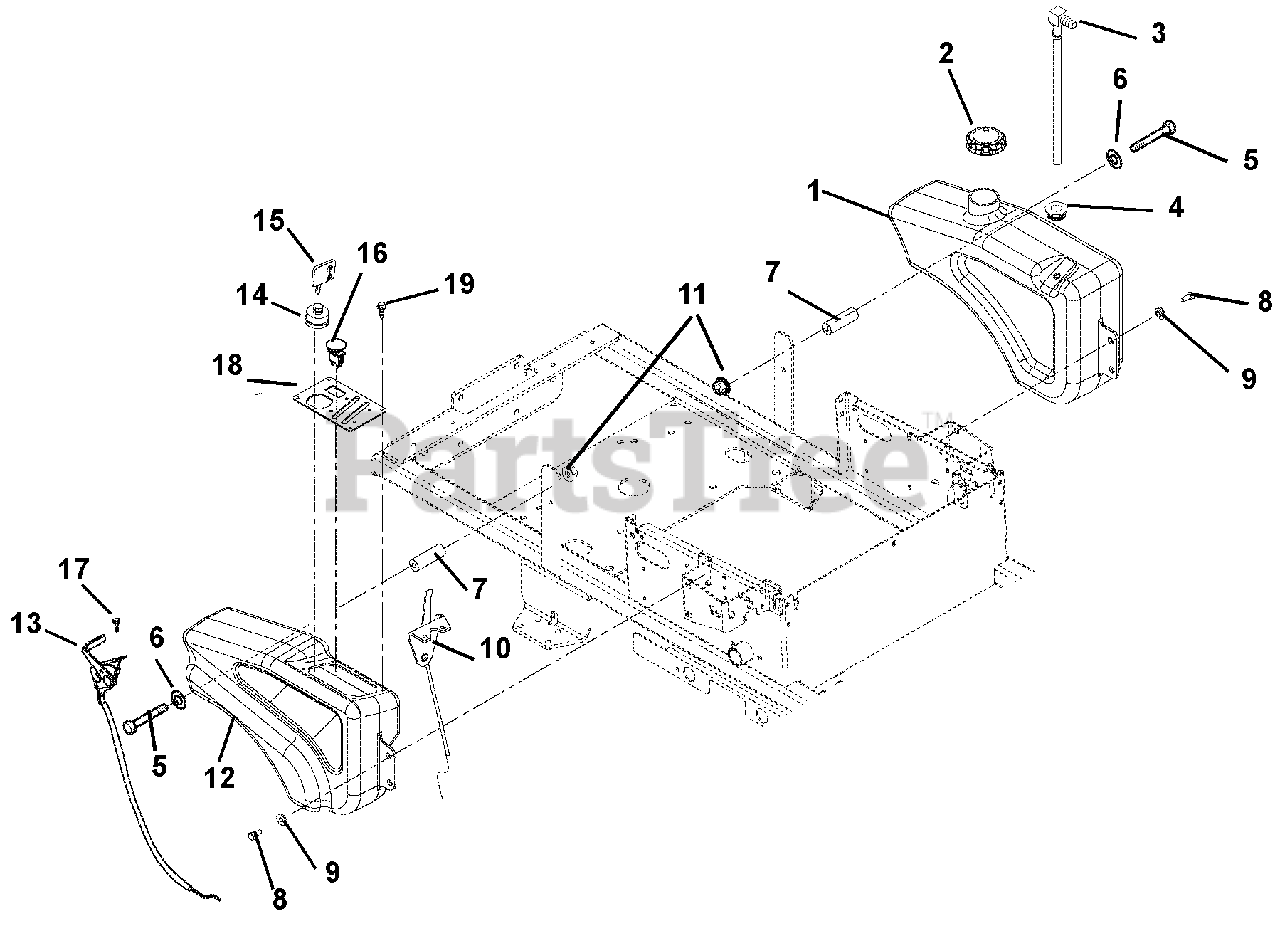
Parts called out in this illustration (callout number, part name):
1	GAS TANK, ZOOM
2	FUEL CAP
3	FITTING, TANK
4	BSHG-FLG .375 X 1.062 X .625 R
5	@BLT-HEX .31-18X3.50 GR5 YWZC
6	@WSHR-FL-STL.38X.875X.083 YWZC
7	SPCR, FLG .32X.49X.15X2.64
8	@BLT-HEX .31-18X.75 GR5 YWZC
9	BSHG, FLG .325X.499X.26X.88
10	CABLE, CHOKE
10	THROTTLE/CHOKE CABLE
11	@NUT-LK-NYL-FLG .31-18 YWZC
12	FENDER, ZOOM
13	CABLE, THROTTLE
14	KEY SWITCH
15	KEY -W/CAP
16	SWITCH, CLUTCH
17	@SCR-TAP 10-24X.50 HWH TR YWZC
18	PANEL, ZOOM CONTROL
18	CONTROL PANEL
19	RIVET, PLASTIC .195 DIA.
